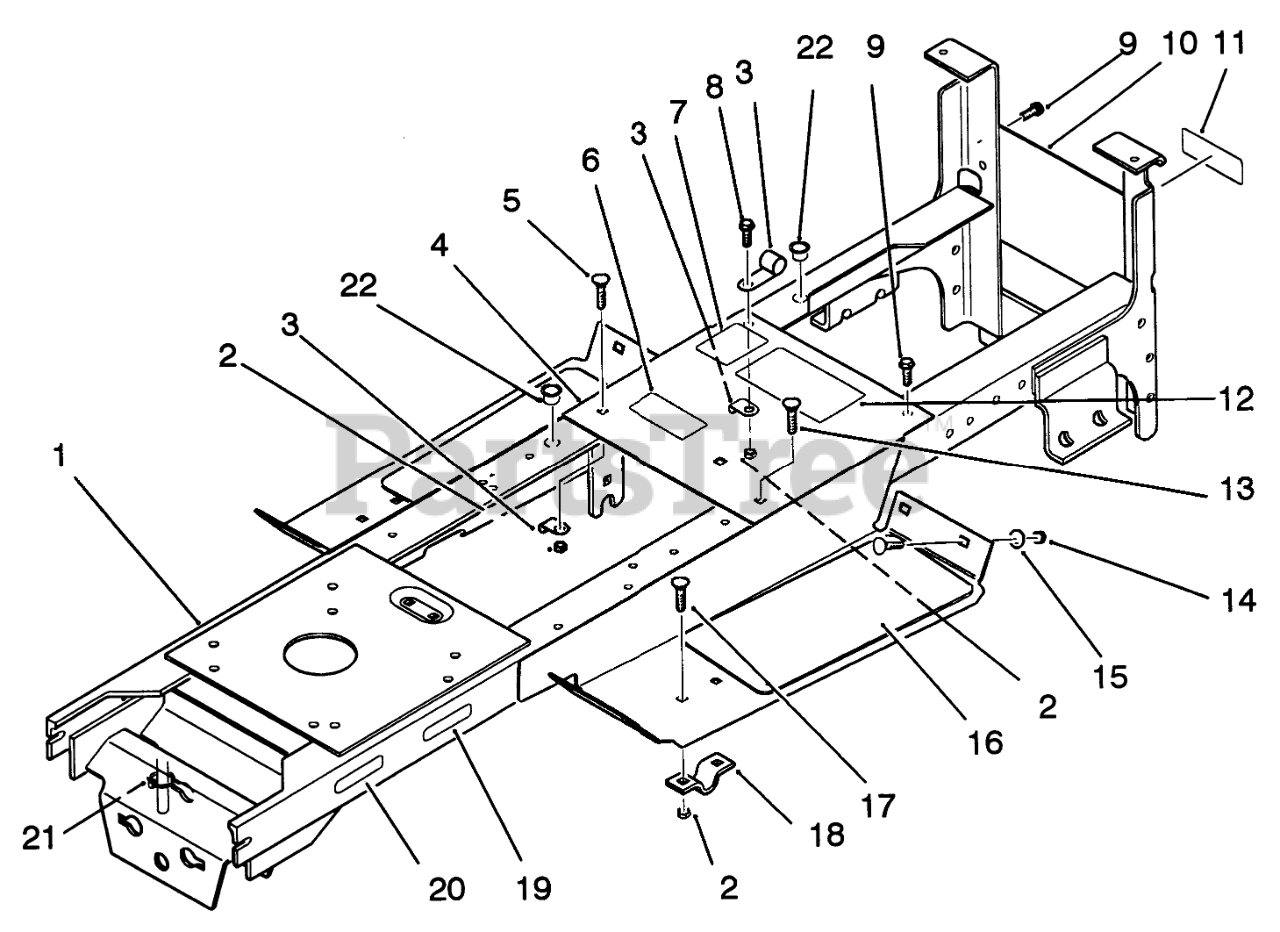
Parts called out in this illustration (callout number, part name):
1	Frame
2	NUT-LOCK, NI
3	THROTTLE CONTROL CLP
4	Panel
5	Bolt-Carriage
6	DECAL-DANGER
7	DECAL-PARKING BRAKE
8	Bolt
9	Screw
10	PANEL-REAR R
11	DECAL-DANGER
12	DECAL-DANGER
13	Bolt-Carriage
14	NUT-HEX
15	WASHER - FLAT YZ
16	PAD FOOTREST
17	NUT-HEX, JAM
18	CLAMP
19	Decal-Attac-O-Matic
20	DECAL-INSTALL BELT
21	PLASTIC TIE
22	BUSHING
